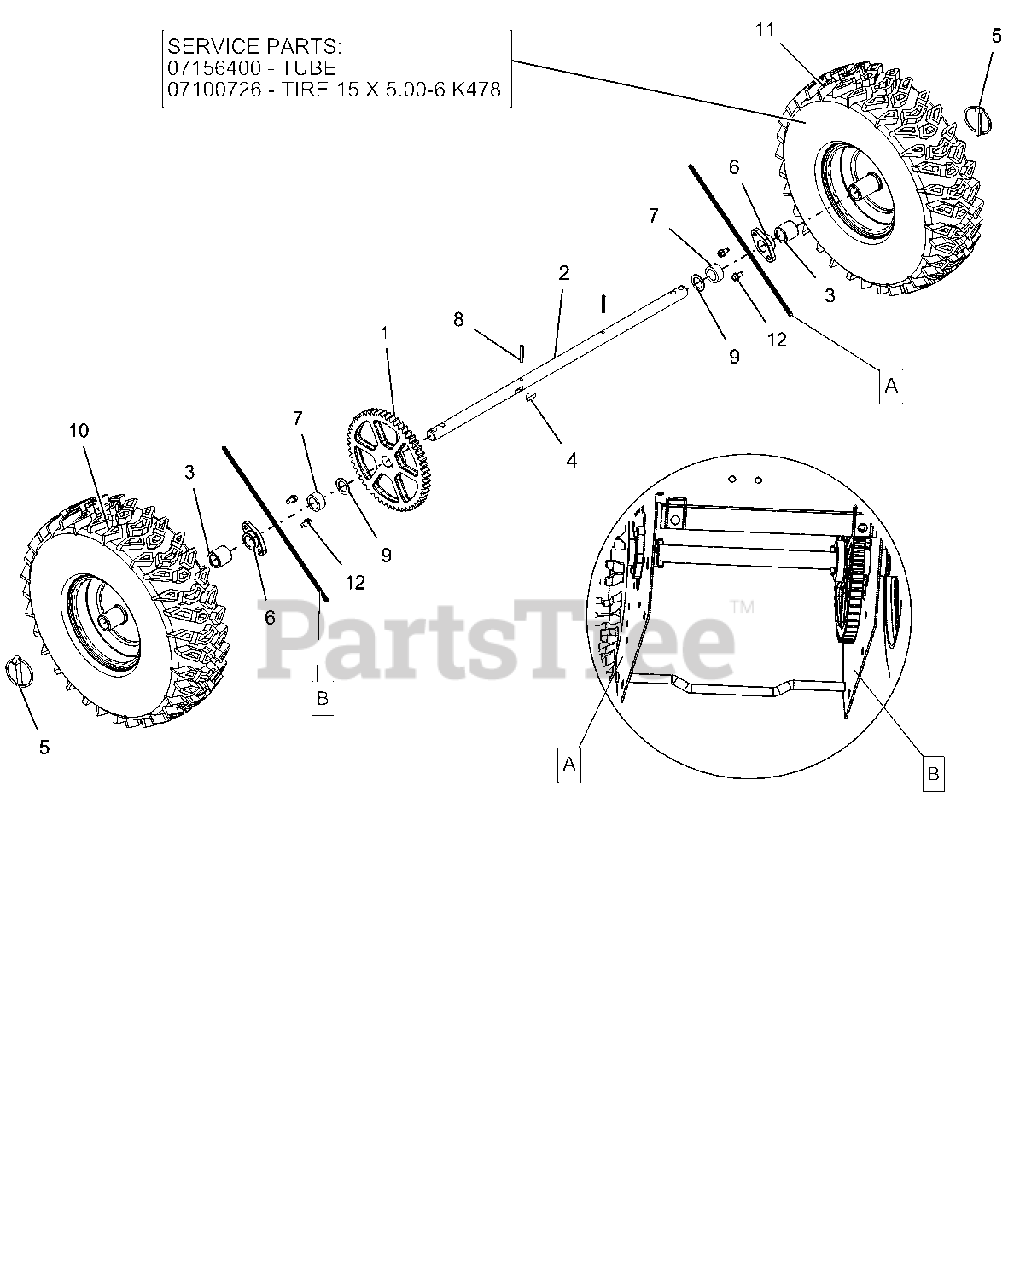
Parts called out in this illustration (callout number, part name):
1	SPUR GEAR, 54T .75ID X 6.75PD
2	AXLE, COMPACT 920,XXX 15" TIRE
3	BSHG-SLV .75X1.12X1.062 NYL BK
4	KEY-WDRF .25X.750X.313 SAE91
5	PIN-LOK .31X1.75
6	BSHG .75X1.125X.65
7	BSHG-SLV .766 X 1.125 X .500
8	PIN-ROLL .188X1.25
9	WSHR-FL-STL.754X1.125X.062YWZC
10	TIRE/WHEEL, RH 15X5.00-6 PIN
11	TIRE/WHEEL, LH 15X5.00-6 PIN
12	SCR-TAP .25-20X.50 HWH TR YWZ
13	TUBE 15 X 5.00-6
14	TIRE, 15X5.00-6 K478
